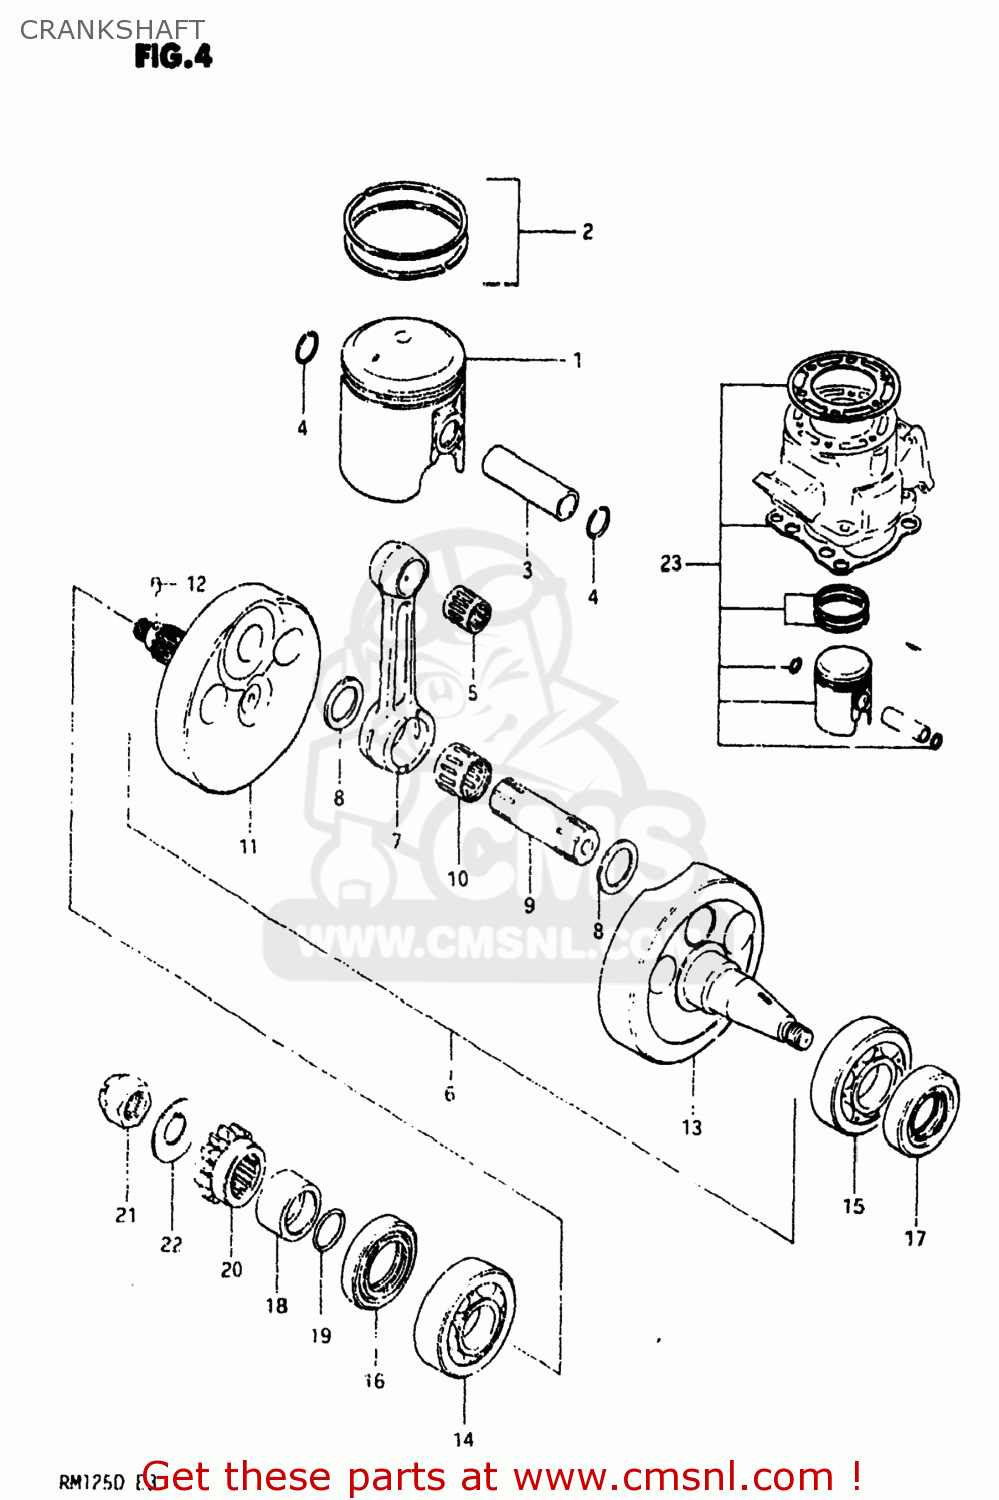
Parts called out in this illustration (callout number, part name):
1	PISTON
2	RING SET,PISTON
3	PIN,PISTON
4	RING,SNAP 14MM
5	BEARING
6	CRANKSHAFT ASSEMBLY
7	CONNECTING ROD
8	WASHER(19X34X1)
9	PIN,CRANK
10	BEARING
11	CRANKSHAFT
12	PIN 3X5
13	CRANKSHAFT,LEFT
14	BEARING
15	BEARING
16	SEAL,OIL(28X40X8)
17	SEAL,OIL(18X30X8)
18	SPACER,PRIMARY DRIVE GEAR
19	O RING(D:2.4,ID:19.8)
20	GEAR,PRIMARY DRIVE
21	NUT
22	WASHER
23	PISTON SET
